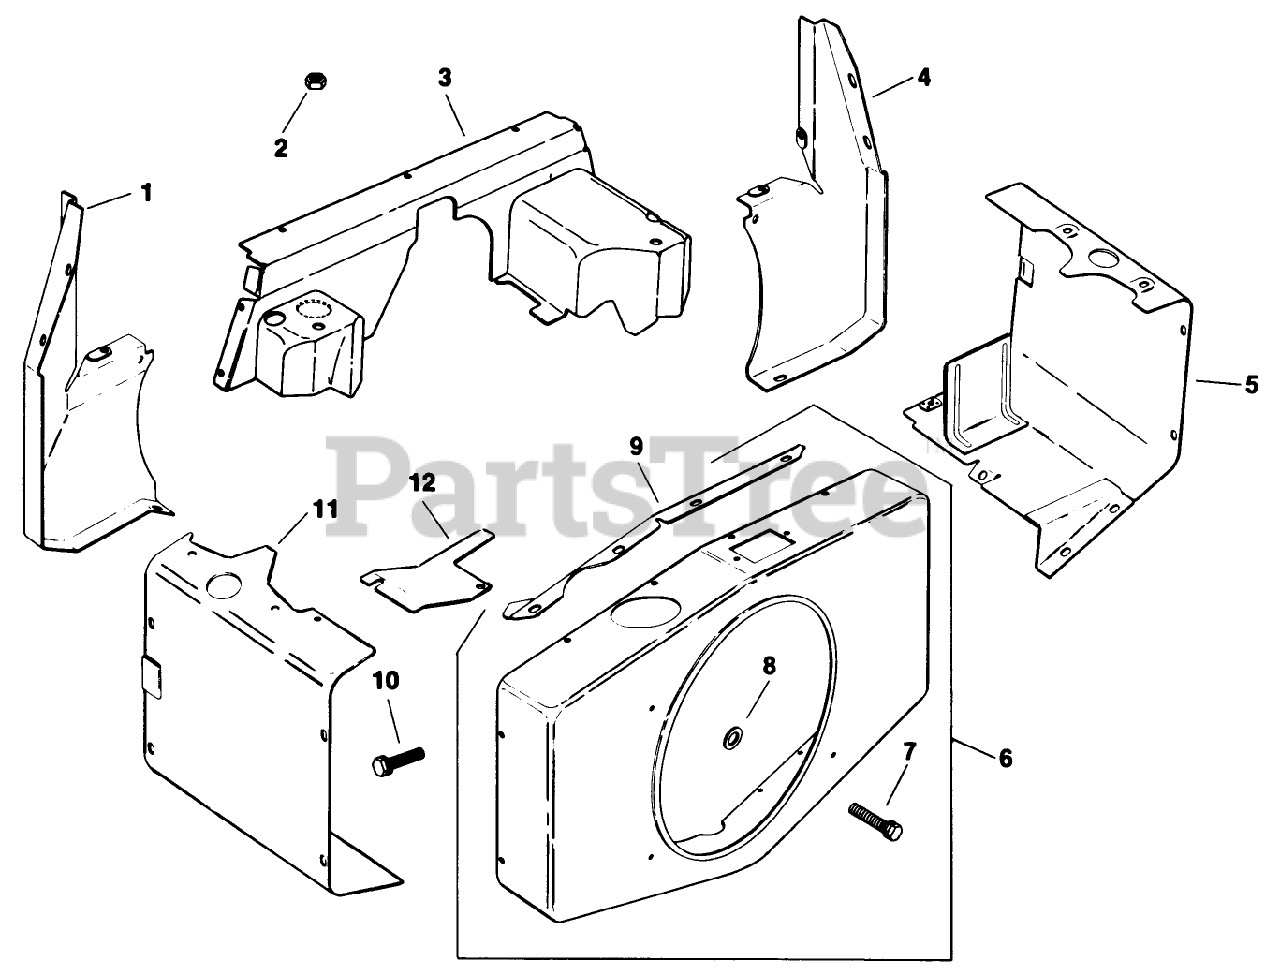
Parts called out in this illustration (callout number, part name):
1	Duct-#1 Side Air
2	Nut
3	Cover-Air Duct
4	Duct-#2 Side Air
5	Baffle-#1 Cylinder Head
6	Kit-Blower Housing(Incl. Ref. #7, 8 & 12)
7	Screw-H.C
9	Screw
10	Baffle-Cylinder Head
11	Baffle-Cylinder Head
12	Support-Upper Housing
